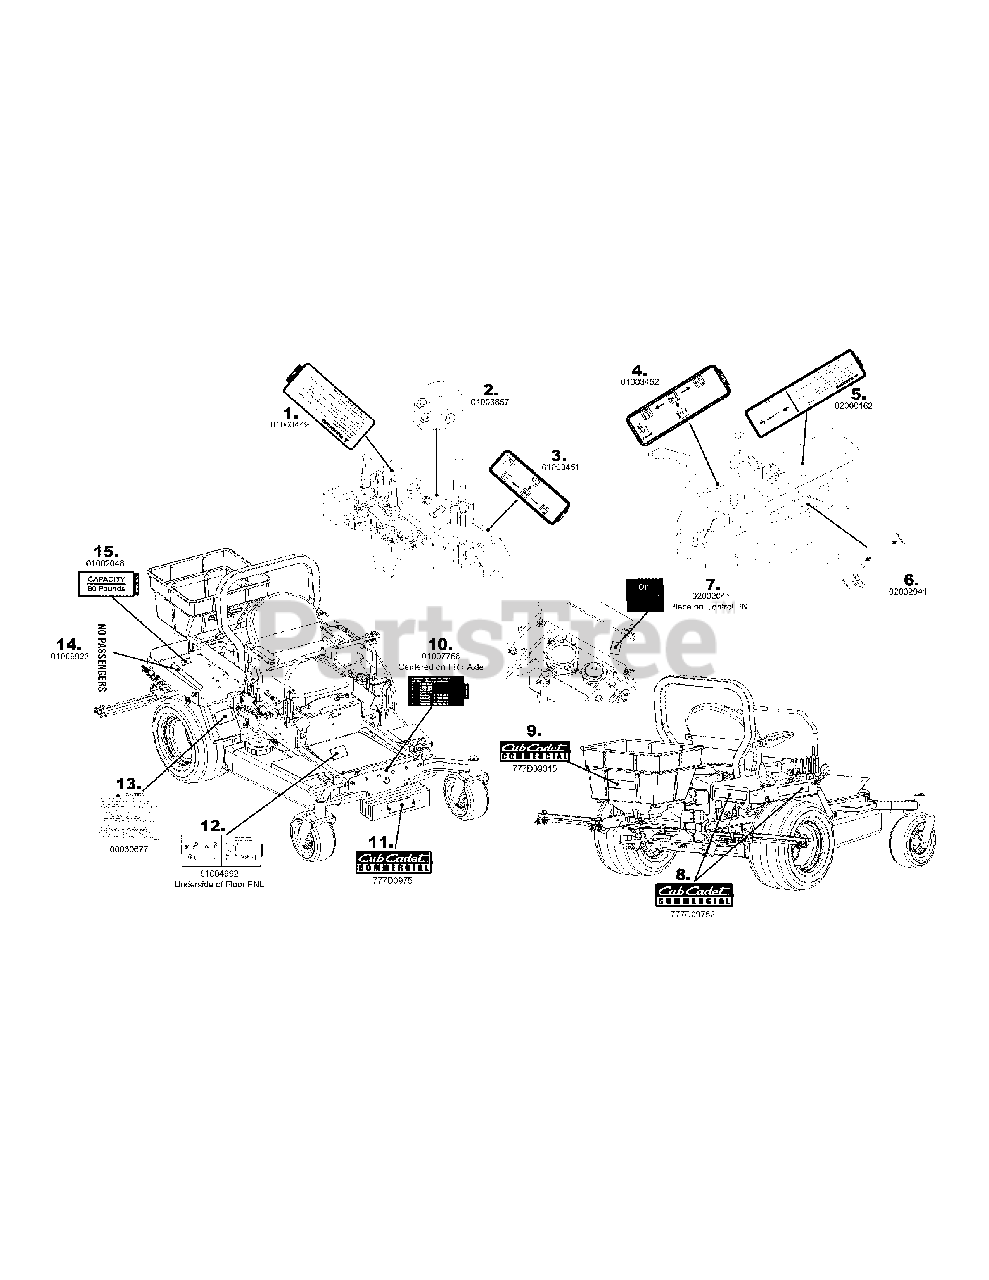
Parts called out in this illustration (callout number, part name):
1	LABEL-RH CONSOLE
2	LABEL-IGNITION
3	LABEL-RH CONTROL
4	LABEL-LH CONTROL
5	DECAL-WARNG/THROT LH CNSL
6	DECAL-SIDE DEFLECTOR ON/OFF
7	LABEL-15W/40 RIMULA
8	LABEL-CUB CADET COMM
9	LABEL-CCC FRONT
10	PATENT LABEL- TOP OF FRONT RAIL
11	LABEL-CUB CADET COMM
12	LABEL-BELT/LUBE
13	LABEL-SAFETY PROCE
14	DECAL-NO PASSENGERS
15	LABEL-80# CAPACITY
